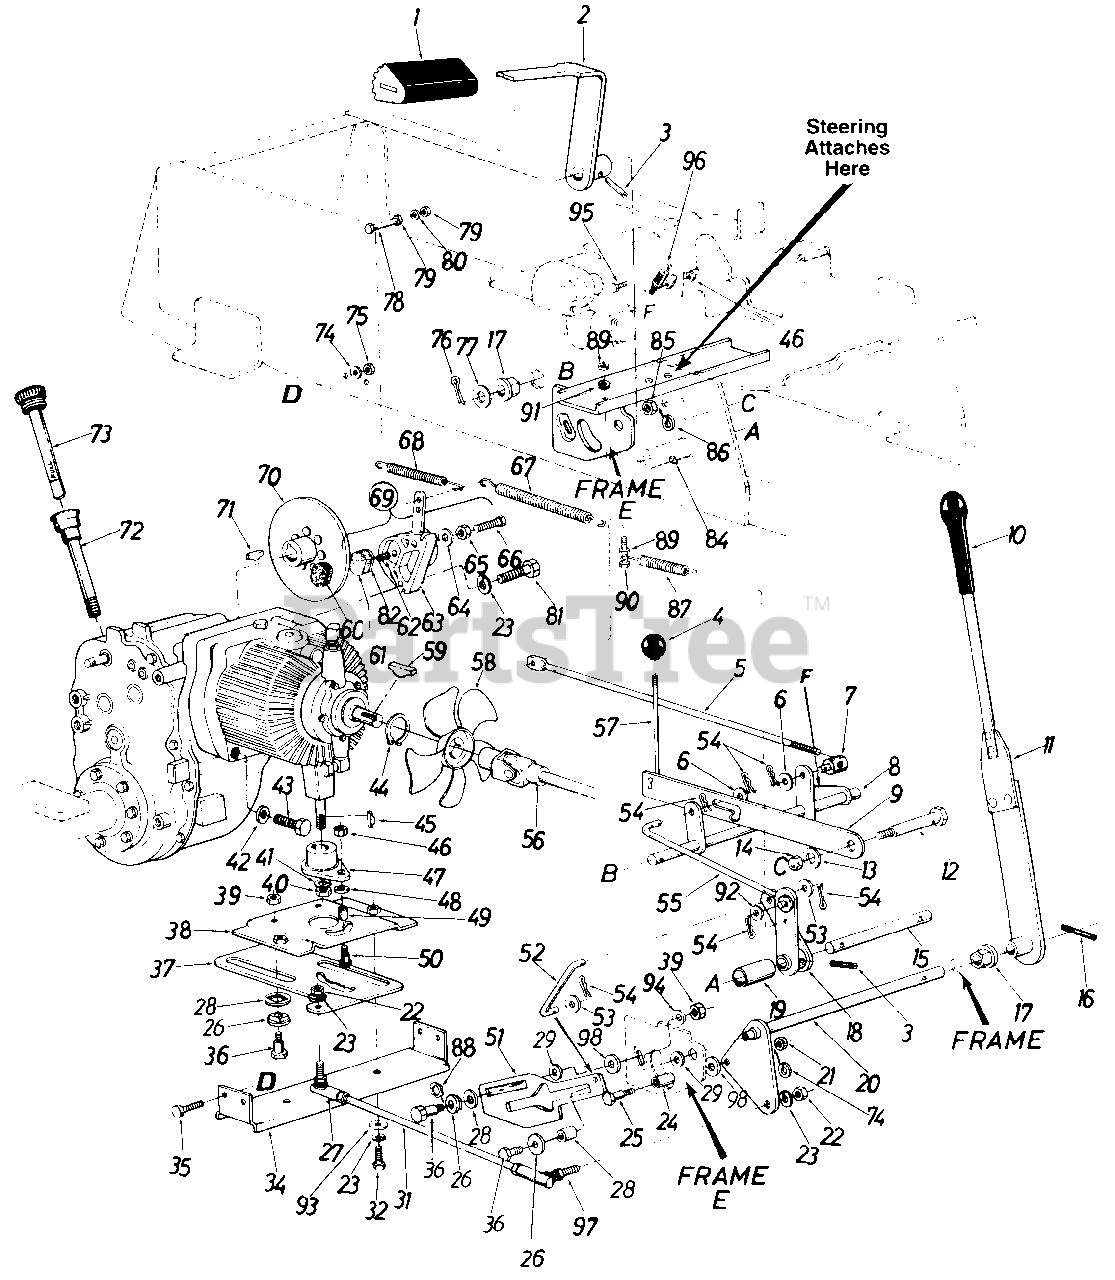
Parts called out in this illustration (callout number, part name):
1	Foot Pad
4	Ball Knob - Brake
5	Brake Rod
6	Fl-Wash. .375" I.D. x 1.00" O.D. x .030"
7	Ferrule
8	Brake Transfer Shaft Ass'y.
9	Parking Brake Cam
11	Control Arm Ass'y. Comp.
12	Shld. Bolt .62" Dia. x 2.75" Lg.
13	Fl-Wash. .460" I.D. x 1.24" O.D. x .06"
14	Push Speed Nut for .625" Dia. Shaft
15	Brake Pivot Shaft
16	Spring Pin Spiral 1/4" Dia. x 1.50" Lg
17	Hex Flange Brg. Plastic .62" I.D.
18	Brake Hub Ass'y.
19	Spacer
20	Control Handle Shaft Ass'y.
21	Hex Cent. L-Nut 5/16-18 Thd.
22	Hex Nut 3/8-24 Thd.
23	L-Wash. 3/8" I.D.
24	Spacer
25	Shoulder Bolt
26	Fl-Wash. 7/16" I.D. x 1-3/8" O.D.
27	Ball Joint Ass'y. 3/8-24 Thd.- L.H.
28	Spacer
29	Fl-Wash. .325" I.D. x 1.25" O.D.
31	Tie Rod
32	Hex Bolt 3/8-16 x .75" Lg.
34	Support Channel
35	Hex Bolt 5/16-18 x .75" Lg.
36	Shld. Bolt .437" Dia. x .268"
37	Cam Plate
38	Slide Mtg. Plate Ass'y.
39	Hex Cent. L-Nut 5/16-18 Thd.
40	Hex Nut 1/2-13 Thd.
41	L-Wash. 1/2" I.D.
42	Fl-Wash. .385" I.D. x .87" O.D. x .060"
43	Socket Hd. Scr. 3/8-16 x 2.75" Lg.
44	Snap Ring
45	#5 Hi-Pro Key 1/8" x 5/8" Dia.
46	Hex Cent. L-Nut 1/4-20 Thd.
47	Pintle Plate Ass'y.
48	Fl-Wash. .281" I.D. x .50" O.D. x .063"
49	Needle Brg. .31" I.D. x .50" O.D. x .437" Lg.
50	Shld. Bolt .31" Dia. x .500
51	Neutral Control Slide
52	Neutral Control Rod
53	Fl-Wash. .312" I.D. x.630" O.D. x .063"
54	Hairpin Cotter
55	Brake Link Rod Ass'y.
56	Universal Joint Ass'y. Comp.
57	Parking Brake Link
58	Fan Ass'y.
59	#61 Hi-Pro Key 3/16 x 5/8" Dia.
60	Lining - Brake
61	Lining - Brake
62	Actuator Pin
63	Housing with Lever and Pin
65	Nut
66	Adjustment Pin
67	Extension Spring .50" O.D. x 6.5" Lg.
68	Extension Spring (Brake Return)
69	Disc Brake Ass'y. Comp.
70	Brake Disc Ass'y.
71	Hi-Pro Key 3/16 x 3/4" Dia.
72	Dipstick Tube Ass'y.
73	Dipstick Ass'y.
74	L-Wash. 5/16" I.D.
75	Hex Nut 5/16-18 Thd.
76	Cotter Pin 1/8" Dia. x 1.00" Lg.
77	Fl-Wash. .635" I.D. x 1.00" O.D. x .120" Thk.
78	Hex Scr. 1/4-20 x 2.50" Lg.
79	Hex Nut 1/4-20 Thd.
80	L-Wash. 1/4" I.D.
81	Hex Scr. 3/8-16 x 1.25" Lg.
82	Backing Plate
84	Grease Fitting
85	Hex Nut 7/16-20 Thd.
86	L-Wash. 7/16" I.D.
87	Extension Spring
88	Wave Wash.
89	Hex Nut 1/4-20 Thd.
90	Hex Bolt 1/4-20 x 1.25" Lg.
91	L-Wash. 1/4" I.D.
92	Fl-Wash.
93	Fl-Wash. .38" I.D. x 1.25" O.D.
94	Bell-Wash.
95	Hex Bolt 1/4-20 x 1/2" Lg.
96	Safety Switch (Clutch)
97	Ball Joint Ass'y. 3/8-24 Thd.- R.H.
98	Fl-Wash. .32" I.D. x .6" O.D.
